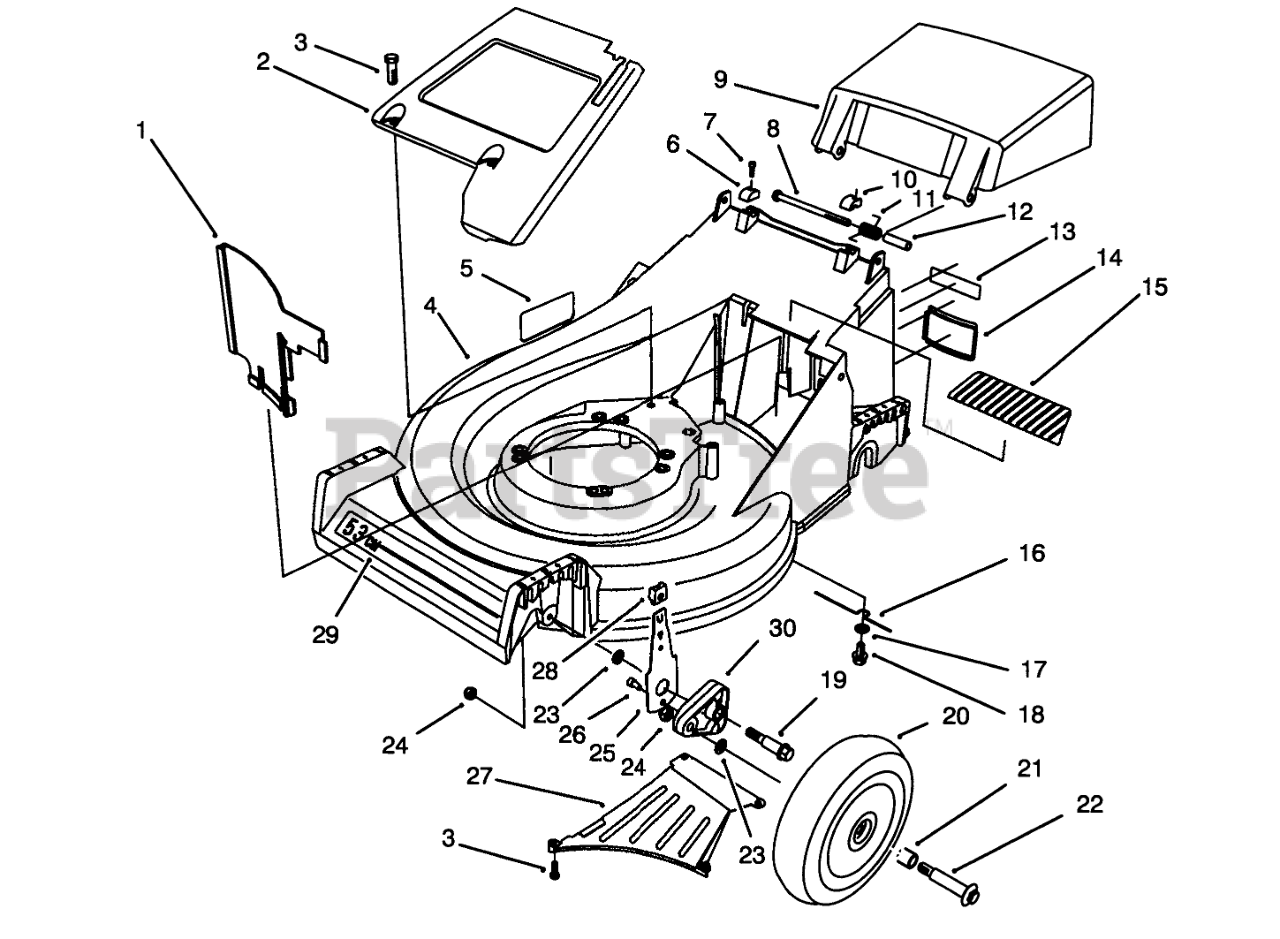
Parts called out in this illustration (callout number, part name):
1	PANEL-VERTICAL
2	PaneI-Screen
3	SCREW-HWHTF
4	Housing-53cm (Incl. Ref. #5 & 29)
5	DECAL - DIN/DANGER
6	CAP-HINGE BOLT, RH
7	SCREW-HSH
8	SCREW-HH
9	Door Discharge
10	CAP-HINGE BOLT, LH
11	SPRING-DOOR
12	SPACER-DOOR
13	DECAL FRENCH REGUL.
14	COVER-ACCESS
15	COVER-TOP
16	RETAINER-BELT
17	WASHER-FLAT
18	SCREW-HHFTF
19	BOLT-SHOULDER
20	Wheel & Tire Assembly(Incl. Ref. #21)
21	BUSHING
22	WHEEL BOLT
23	WASHER
24	NUT-LOCK
25	FRONT SPRING ARM ASM
26	SCREW-HSH, THREAD FORMING
27	Ramp-Discharge
28	KNOB-ARM
29	DECAL
30	ARM-PIVOT, FRONT
